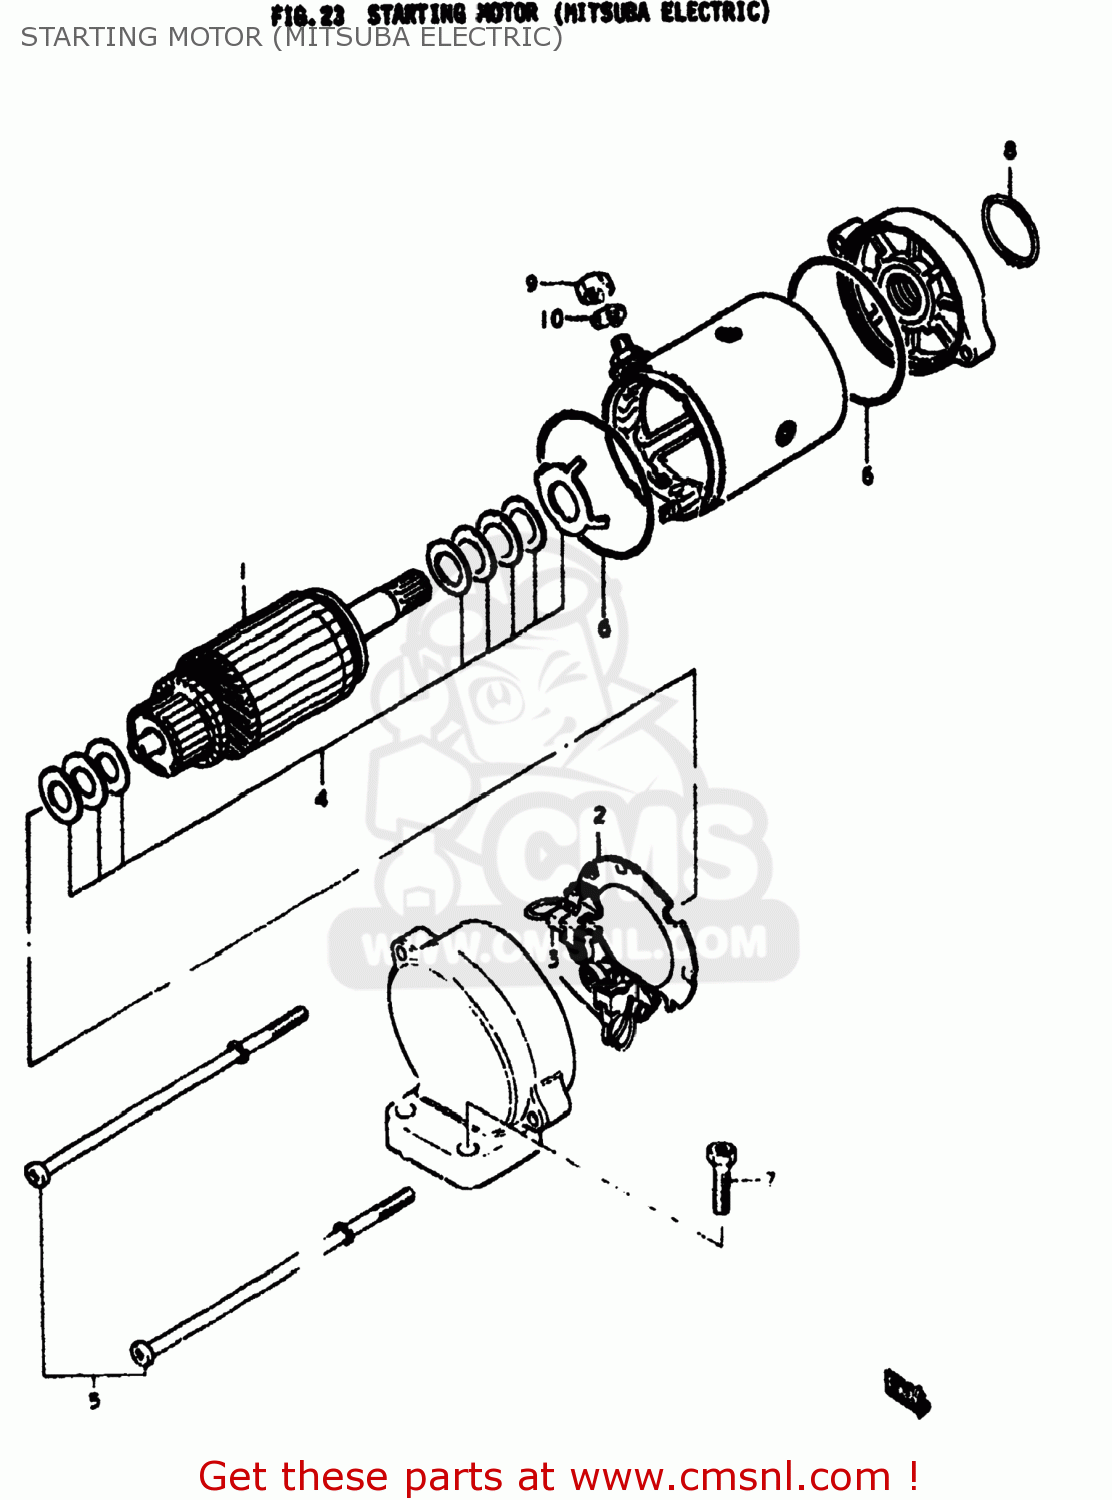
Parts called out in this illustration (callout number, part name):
1	ARMATURE
2	HOLDER ASSY
3	BRUSH SET
4	SHIM SET
5	BOLT,STARTING MOTOR HOUSING
6	O RING
7	SCREW
8	O RING(D:2,ID:24.5)
9	NUT 6MM
10	LOCK WASHER
